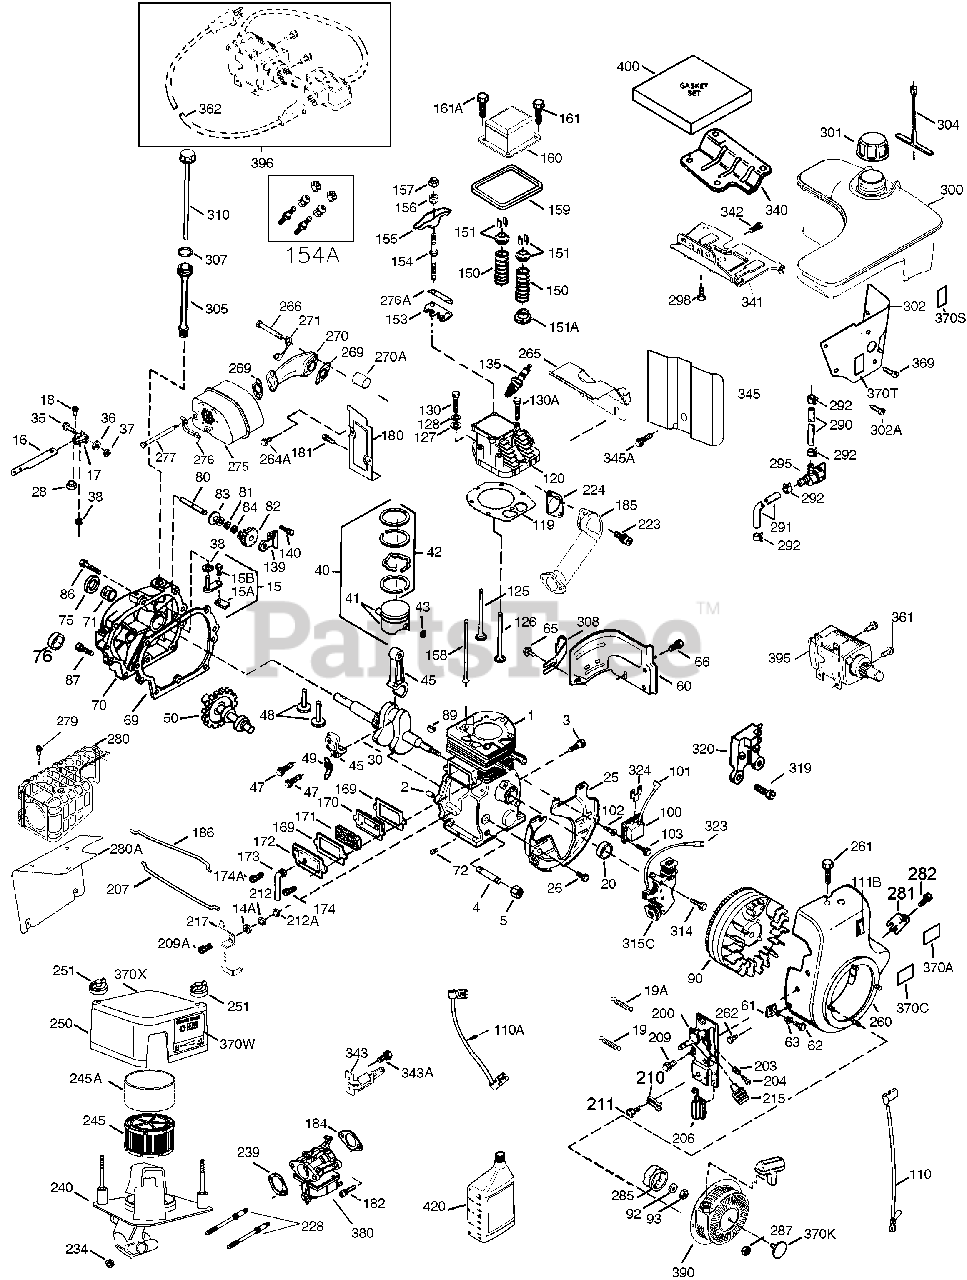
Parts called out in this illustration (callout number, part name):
1	"Cylinder (Cast Iron Liner) (3-5/16") (Incl 2, 20, 72, 72A) Incl. 2, 20, 72 , 72A & 72B
2	Dowel Pin
14	Flat Washer
15	Governor Rod (Incl. 15A & 15B)
15A	Governor Yoke
15B	Screw, 6-40 X 5/16"
16	Governor Lever Assembly (Incl. 212A)
17	Governor Lever Clamp
18	Screw, T-15, 8-32 X 7/16"
19	Governor Spring
19D	Extension Spring & Throttle Bracket
20	Oil Seal
25	Blower Housing Baffle
26	Screw, 1/4-20 X 19/32"
28	Lock Nut, 8-32
30	Crankshaft
35	Screw, 10-32 X 3/4"
36	Lock Washer #8
37	Lock Nut, 10-32
38	Retaining Ring
40	Piston, Pin & Ring Set (Std.) (Incl. 41, 42 & 43)
40	Piston, Pin & Ring Set (.010" OS) (In cl. 41, 42 & 43)
42	Ring Set (Std.) (3-1/8")
42	Ring Set (.010" OS)
43	Piston Pin Retaining Ring
45	Connecting Rod Assembly (Incl. 47 & 4 9)
47	Connecting Rod Bolt (1/4-20 X 1-5/16" )
48	Valve Lifter
49	Oil Dipper
50	Camshaft (MCR)
60	Blower Housing Extension
62	Screw, 8-32 X 3/8"
65	Screw, 10-24 X 9/16"
69	Cylinder Cover Gasket
70	Cylilnder Cover (Incl. 20,71,80-84)
71	Crankshaft Bushing
72	Oil Drain Plug (Sq. Hd., 1/4-18)
72A	Oil Drain Plug (Internal Hex., 1/4-18 ) (Headless, Tapered, Countersunk)
80	Governor Shaft
82	Governor Gear Ass'Y. (Incl. 81)
83	Governor Spool
84	Retaining Ring
86	Screw, 1/4-20 X 1-3/16"
87	Screw, 1/4-20 X 1- 11/16"
89	Flywheel Key
90	Flywheel (3/5 Split) Or (7-Amp.), W/R ing Gear)
92	Belleville Washer
93	Flywheel Nut (5/8-18)
100	Solid State Ignition (Incl. 101)
101	Spark Plug Cover
102	Solid State Mounting Stud
103	Screw, T-15, 10-24 X 15/16"
110A	Ground Wire - Black 7.0"
110A	Ground Wire
110B	Ground Wire (6.75" - black - female & ring terminals)
111B	Rocker Switch (On/Off)
119	Cylinder Head Gasket
120	Cylinder Head (Incl. 151A & 270A)
125	Exhaust Valve (Std)
126	Intake Valve (Std.)
127	Flat Washer
128	Belleville Washer
130	Screw, 5/16-18 X 2-1/2"
135	Resistor Spark Plug (Rn4C) also avail able in Packaged Part #740069
150	Valve Spring
151	Valve Spring Keeper
151A	Intake Valve Seal
153	Push Rod Guide
154	Rocker Arm Stud
155	Rocker Arm
156	Rocker Arm Bearing
157	Lock Nut
158	Push Rod
159	Rocker Arm Cover Gasket
160	Rocker Arm Cover
161	Screw, T-30, 1/4-20 X 1/2"
169	Valve Cover Gasket
170	Breather Body
171	Breather Element
172	Valve Cover
173	Breather Tube
174	Screw, 10-24 X 1/2"
178	Nut & Lock Washer 1/4-28
180	Blower Housing Extension
183	Remote Choke Bracket
184	Carburetor-To-Intake Pipe Gasket
185	Intake Pipe (Incl. 223)
186	Governor Link
200	Remote Control Bracket (Rv) (Incl. 20 3 & 204)
203	Compression Spring
204	Screw, T-10, 5-40 X 7/16"
207	Throttle Link
210	Conduit Clip
211	Screw, 10-32 X 9/32"
212	Bushing (Incl. 14A & 213)
212A	Bushing
213	Screw, 10-24 X 29/32"
216	R.P.M. Adjusting Lever
217	Bellcrank Lever
223	Screw, T-30, 5/16-18 X 1-3/32"
224	Intake Pipe Gasket
228	Air Cleaner Stud
239	Air Cleaner Gasket
240	Air Cleaner Body
245	Air Filter Also available in 740111 m erchandiser package.
245A	Air Filter (Poly)
250	Air Cleaner Cover
251	Wing Nut, 1/4-20
260	Blower Housing
262	Screw, 5/16-18 X 9/16"
265	Cylinder Head Cover
266	Screw, 5/16-18 X 1-9/32" (Manifold Sh oulder Screw)
269	Exhaust Manifold Gasket
270	Exhaust Manifold
270A	Exhaust Port Liner
271	Locking Plate (Manifold)
275	Muffler (With Mounting Brackets)
276	Locking Plate
277A	Screw, 5/16-18 X 4-1/2" (Muffler Shou lder Screw)
280	Heat Shield
285	Starter Cup
290	Fuel Line (32.0" Length) Low Permeati on
292	Fuel Line Clamp
298	Screw, 1/4-15 X 3/4"
300A	Fuel Tank (Incl. 292 & 301) (4-Qt.) ( Premium Style)
301	Fuel Cap (Red Plastic) ( 1-1/2" I.D.)
302	Fuel Tank Extension (NO Electric-Star t Provision) used with Premium Tank
305	Oil Fill Tube
308	Fill Tube Clip
309	Screw, 10-32 X 5/16"
310	Dipstick
311	Oil Fill Plug (Incl. 312)
312	Oil Fill Plug Gasket
314	Screw, 1/4-20 X 3/4"
319	Screw, 10-24 X 3/8"
320	Regulator (5 & 7 Amp)
323	Female Blade Terminal
324	Terminal
338	Screw, 10-32 X 1/2"
341	Fuel Tank Bracket (Lower) (Premium Ta nk)
342A	Screw, 5/16-18 X 7/8"
345	Heat Baffle
355	Starter Handle (Standard)
361	Screw, T-30, 1/4-20 X 15/32" (Electri c Starter Mounting Screws)
370	Decal - Tecumseh Logo For Top Of Reco il Starter
370	Decal - Climate Guard - Above 32 Degr ees F.
370	Decal - Climate Guard - Below 32 Degr ees F.
370	Decal - Low Oil Sentinel - Set Of Lig ht & Switch Information
380	Carburetor (Incl. 184)
390	Rewind Starter Summer Pulley
395	Electric Starter Motor (12 Volt) (Inc l. 361)
414	Spark Arrestor Screen
420	Sae 30 4-Cycle Engine Oil (Quart) (Su mmer)
704	Screw, 1/4-20 X 5/8"
999	Summer Maintenance Kit includes 20 oz . - SAE30 Oil, spark plug, air filter , fuel stabilizer
